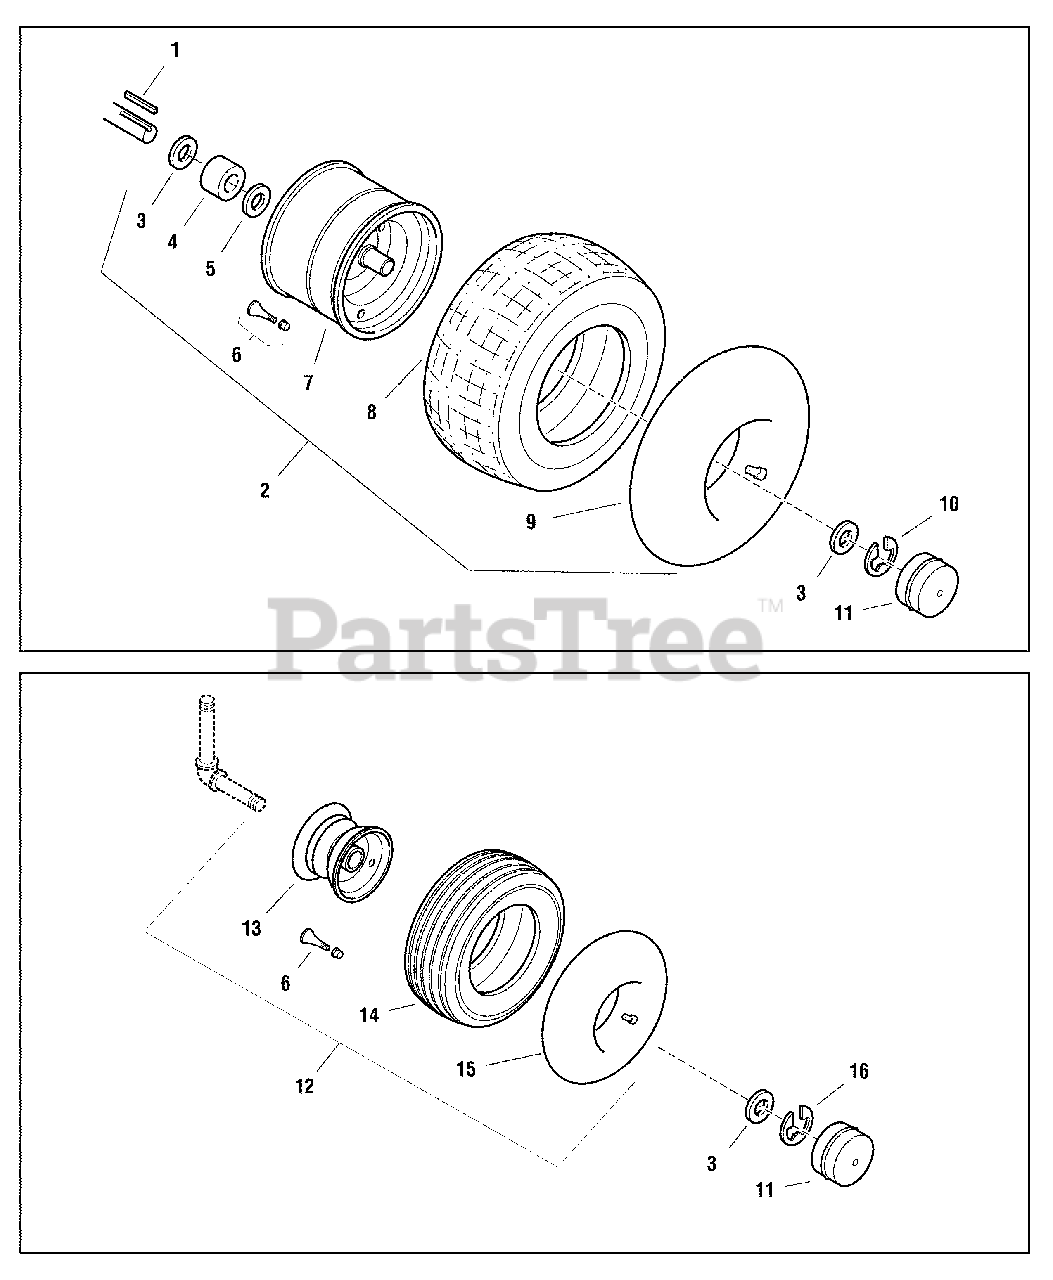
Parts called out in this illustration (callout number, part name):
1	KEY, Square, 3/16 x 3/16 x 1-1/2 long
2	REAR WHEEL & TIRE ASSEMBLY, Hoosier, (Includes Ref. Nos. 3,
3	WASHER, 3/4
4	SPACER
5	WASHER
6	VALVE STEM & CAP
7	REAR WHEEL ASSEMBLY, Metallic Gray
8	TIRE, Rear Wheel, 16 X 6.50-8
9	TUBE, Rear Tire, 16 X 6.50 - 8.00
10	E RING
11	HUB CAP, Silver
12	FRONT WHEEL & TIRE ASSEMBLY, Hoosier, 13 x 5.00-6, Metallic
13	FRONT WHEEL ASSEMBLY 13 x 5.00-6, Metallic Gray (Includes Re
14	TIRE, Front Wheel, 13 x 5.00-6
15	TUBE, Front Wheel, 4.10/3.50 x 6
16	KLIP RING
